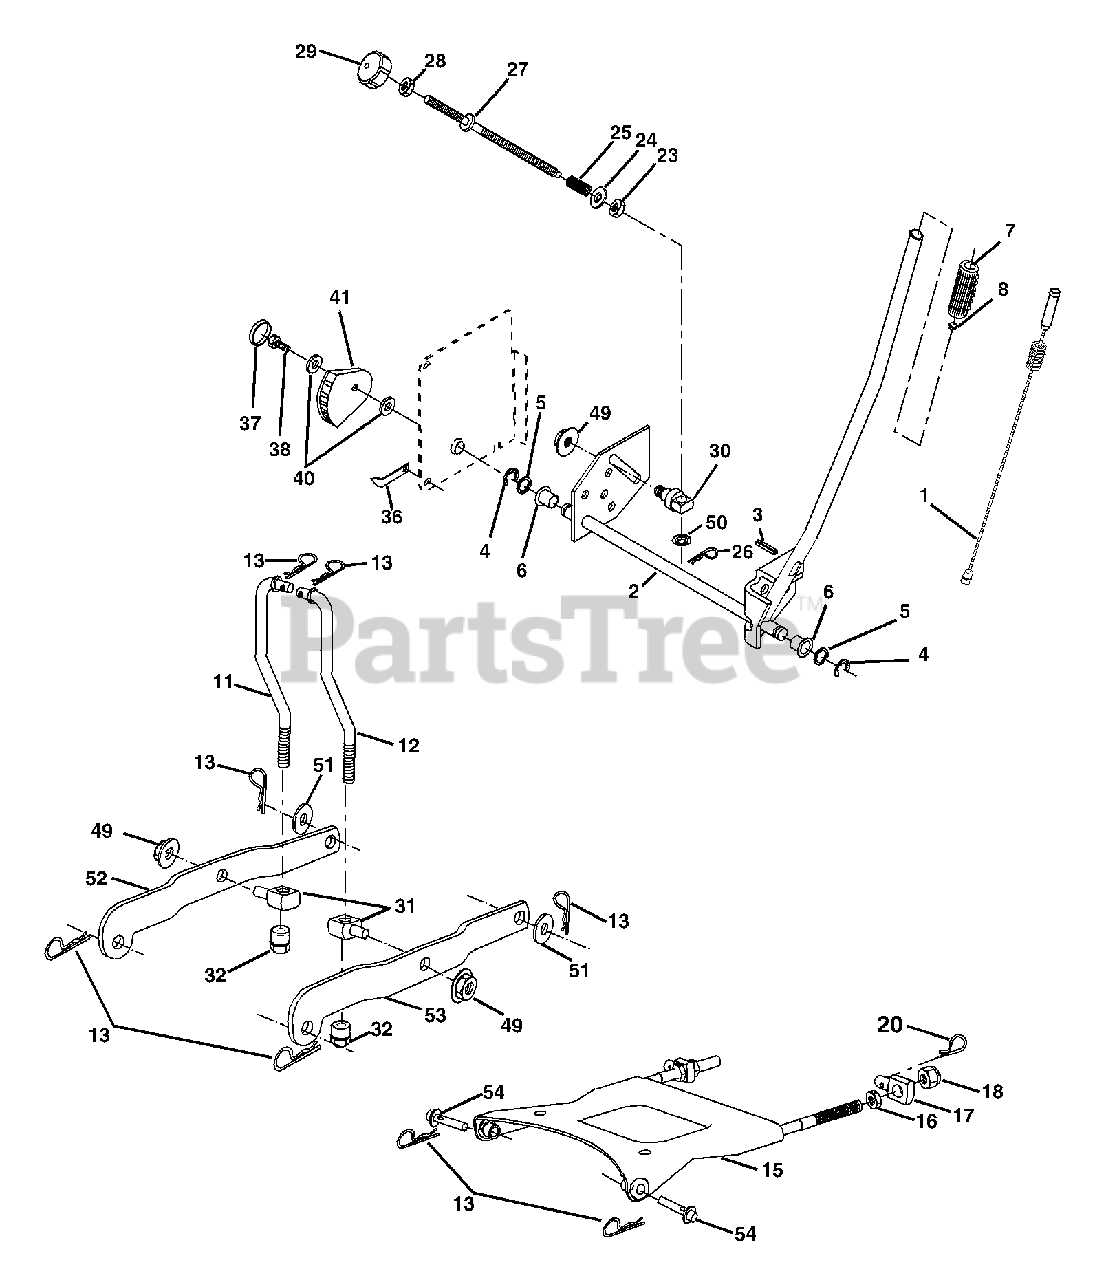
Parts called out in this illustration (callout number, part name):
1	Wire Asm Inner/Spring W/Plunger LT
2	Shaft Asm Lift RH w/Inf
3	Pin Groove 1 500 Zinc
4	E Ring #5133-62
5	Washer 21/32 x 1 x 21 Ga
6	Bearing Nylon Blk 629 Id
7	Grip Handle Fluted Blk
8	Button Plunger Black
11	Link Lift LH
12	Link Lift RH
13	Retainer Spring
15	Plate Asm Susp Front
16	Nut Jam Hex 1/2-13 unc
18	Nut Lock w/Wsh 1/2-13 unc
20	Retainer Spring
23	Nut Special
24	Washer 13/32 x 5/8 x 16 Ga.
25	Spring 2-1/8"
26	Retainer Clip
27	Rod Adj Lift Zinc 7.49 Wrk Lg
28	Nut Hex Jam 3/8-16 unc
29	Knob Inf 3/8-16 Unc Blk W/sym
30	Trunnion Infin Height
32	Nut Lift Link 7/16-20
36	Indicator Height STLT
37	Plug Hole Blk 1.485/1.515 Dia.
38	Screw 5/16-18 x 1
40	Washer 11/32 x 1-1/2 10 Ga.
41	Scale Ind. Height Blk.
49	Nut Hex Flange Lock
50	Nut, Push Phos & Oil
51	Washer 17/32 x 7/8 x 16 Ga.
52	Arm Susp. Rear Lh
53	Arm Susp. Rear Rh
54	Pin Flange
